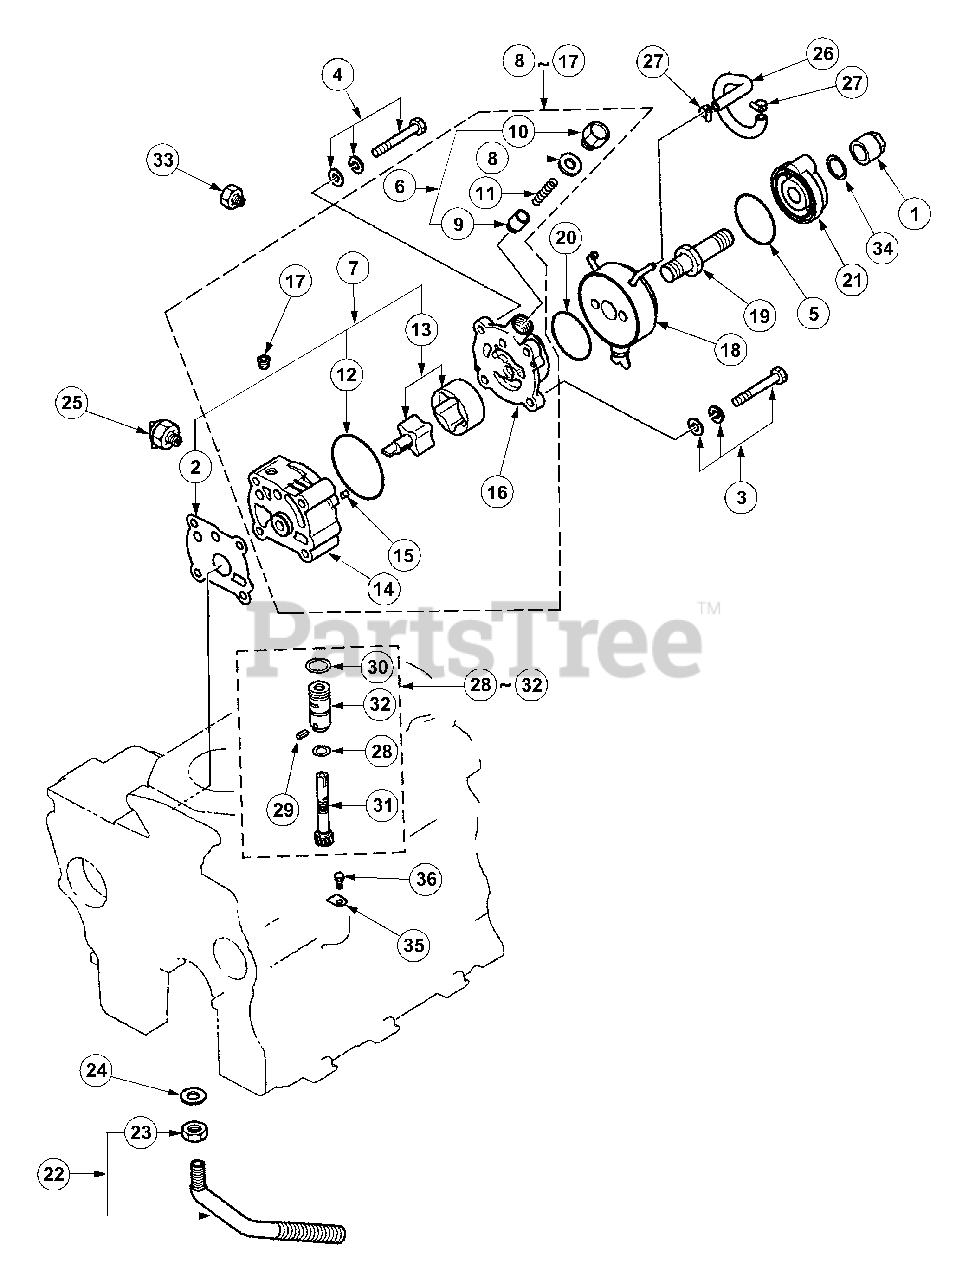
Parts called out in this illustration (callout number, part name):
2	Gasket,Oil Pump
3	Bolt,w/Washer
4	Bolt,w/Washer
5	O-Ring
6	Service Kit,Relief
7	Service Kit,Rotor
9	Plunger,Relief
12	O-Ring
13	Rotor Assy,Oil
14	Body,Oil Pump
15	Pin
16	Cover,Oil Pump
17	Plug,Taper
21	Cover,Oil Pump
22	Screen Assy,Oil
25	Switch,o Il Pressure
29	Pin,Spring
30	O-Ring
31	Gear,Speed
32	Sleeve,Speed
33	Joint,Oil Pipe
35	Plate,Locking
36	Bolt,w/Washer
